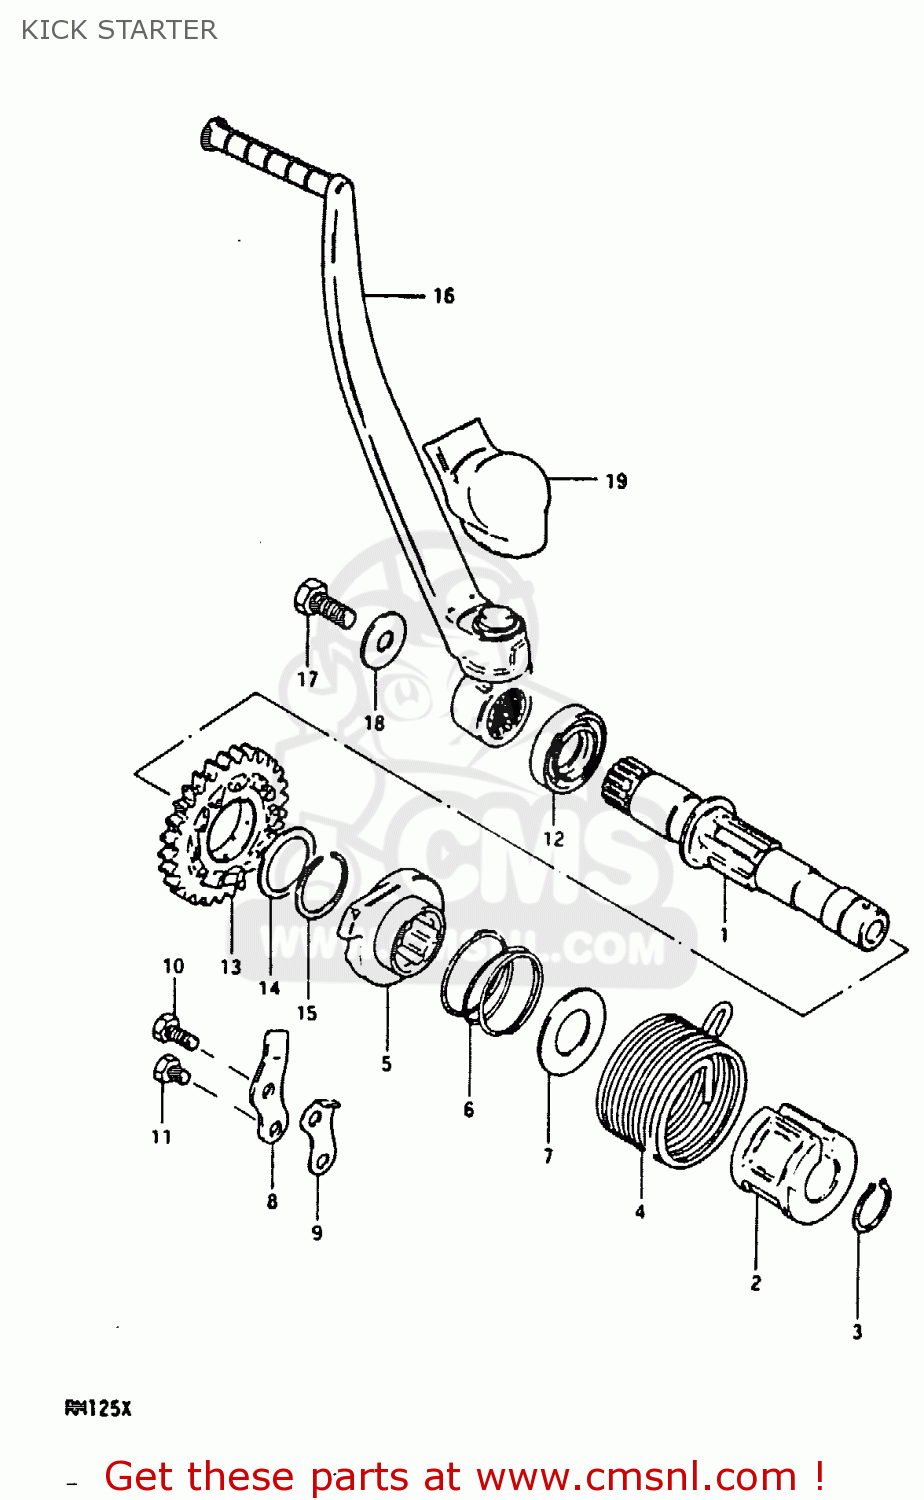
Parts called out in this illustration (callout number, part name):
1	SHAFT,KICK STARTER
2	GUIDE,KICK STARTER SFT SPRING
3	CIRCLIP
4	SPRING
5	STARTER,KICK
6	SPRING
7	WASHER
8	GUIDE,KICK STARTER
9	STOPPER,KICK STARTER
10	BOLT, UPPER
11	BOLT
12	SEAL,OIL(20X27X5)
13	GEAR,KICK STARTER DRIVE
14	SHIM
15	CIRCLIP
16	LEVER ASSEMBLY,KICK STARTER
17	BOLT
18	WASHER(8.2X23X3.2)
19	COVER,KICK LEVER JOINT
